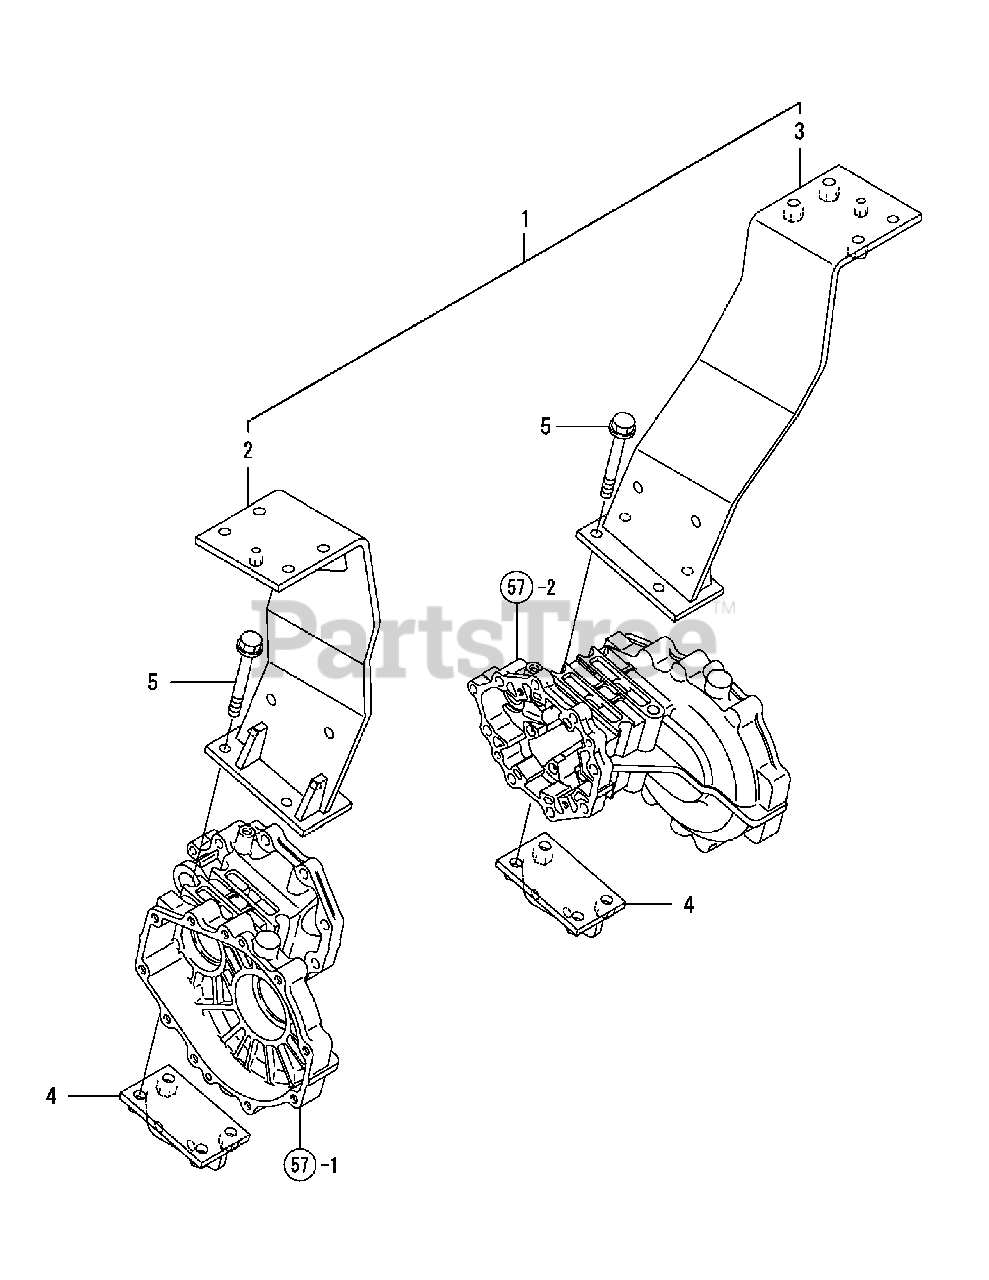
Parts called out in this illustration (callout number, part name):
1	Rops Lower Kit 2520
2	Frame Assy, Lower LH
3	Frame Assy, Lower RH
4	Plate Assy, Lower
